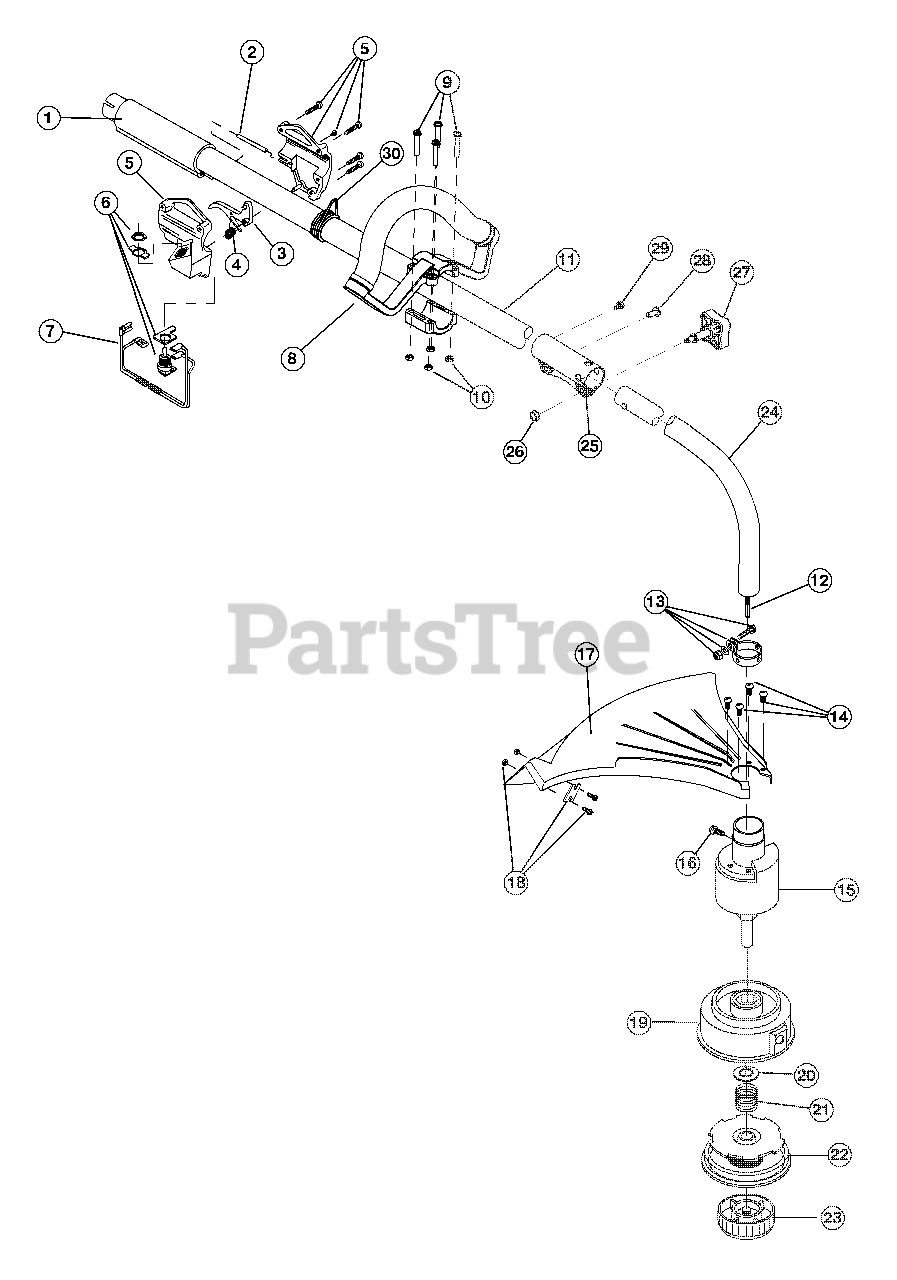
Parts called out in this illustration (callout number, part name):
2	Throttle Cable Assembly
3	Throttle Trigger
4	Throttle Trigger Spring
5	Throttle Trigger Assembly (includes 3 & 4)
6	Switch Assembly
7	Wire Lead Assembly
8	Loop Handle Assembly
10	Nut
11	Upper Drive Shaft Hsg Assembly
12	Lower Flex Shaft
13	Lower Clamp Assembly
14	Shield Mounting Screw
15	Bushing Housing Assembly w/shaft
15	Bushing Housing w/o shaft
16	Anti-Rotation Screw
17	Shield Assembly (includes 18)
18	Blade Assembly
19	Outer Spool Assembly (includes 20)
21	Spring
22	Inner Reel
23	Bumb Knob Assembly
24	Lower Drive Shaft Hsg
25	Split Boom Coupler Assembly (includes 26-29)
26	Nut
27	Knob (includes 26)
30	Harness Clip
